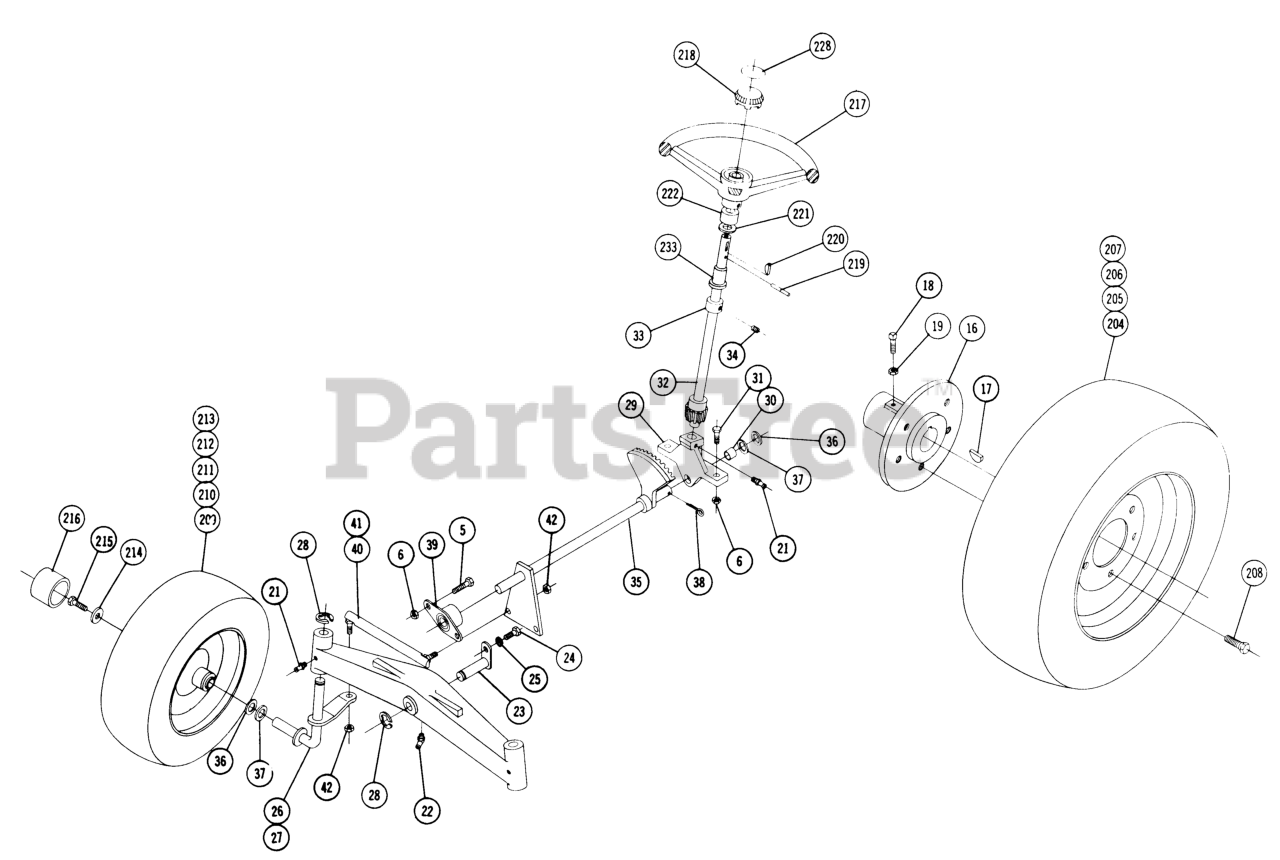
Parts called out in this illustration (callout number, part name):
1	Ass-y.Frame
2	Hoodstand
3	Nut, 1/4-20
4	Cover-Dust
5	Bolt 3/8-16 x 1
6	3/8-16 E.S.
7	Bolt 5/16-18 x
8	Nut-Nylok
9	Pulley
10	Set Screw
11	WOODRUFF KEY
12	Bolt 3/8-16 x 7/8
13	Lockwasher
14	Tool Box
15	Bolt 3/8-16 x 3/4
16	Hub Wheel
17	WOODRUFF KEY
18	Screw-Set
19	3/8-16 Jam Nut
20	AXLE-FRONT
21	Zerk
22	FITTING-GREASE
23	PIN AND PLATE ASM
24	Bolt Hex 5/16-18
25	Lockwasher
26	R.H. Spindle
27	L.H. Spindle
28	E-RING
29	Support
30	BEARING-BRONZE
31	Bolt 3/8-16 x 1
32	ASSY UPPER STEER R
33	Collar
34	Set Screw Nylok
35	Assy-Steering
36	WASHER-SHIM
37	WASHER
38	Cotter Pin
39	BEARING-FLANGED
40	Tie Rod-R.H.
41	Tie Rod-L.H.
42	Locknut 3/8-24
43	Pedal
44	BUSHING
45	Gasket
46	Hairpin
47	Hairpin
48	Roll Pin
49	Lift Lever
50	LOWER PLUNGER R
51	PLUNGER ROD
52	Roll Pin
53	SPRING-COMPRESSION
54	Guide-Rod
55	Cap
56	Grip
57	Hairpen
58	Quadrant
59	ROD-LIFT CONTROL
60	KNOB-LIFT CONTROL
61	Cap
62	Conduit
63	Hitch
64	Pin
65	RING-SNAP, EXTERNAL
66	SPACER
67	BATTERY BOX ASSY R (NS)
68	Nut-Nylok
69	LINK BATTERY CLAMP
70	Nut-Nylok
71	ever Brake
72	Washer
73	E Ring
74	Idler Arm
75	BUSHING-FLANGED
76	Bolt 1/4-20 X 3/4
77	Nut-Jam 1
78	Lockwasher
79	Handle-Brake
80	KNOB
81	Washer
82	SPRING-BRAKE
83	Idler Pulley
84	SPACER-BRAKE LINK
85	Bolt 3/8-16 x 1 5/8
86	Cam Control Arm
87	Indicator-Speed
88	Bolt, 1/4-x 1/2
89	Bearing
90	PIN
92	Cam Pivot Rod
93	FRICTION COLLAR
94	COLLAR BRKT PIVOT
95	FRICTION CONE
96	SPRING FRICTION
97	Collar Friction
98	Nut 3/1-10 Jam
99	WOODRUFF KEY
100	Cam Plate
101	Spacer
102	NYLINER BUSHING
103	SHIM-WASHER
104	Spring
105	Housing
106	Support-Fuel Tank
107	Bolt Hex 5/16-18
108	Bolt 1/4-20 x 5/8 Whizlock
109	Grommet
110	Panel
111	Plug Button
112	SPEED NUT
113	Screw-Self #10 10-16
114	Fuel Tank
115	Clamp-Tank
116	Cap
118	Nut Square
119	S/A FUEL VALVE
120	Hose
121	Clip
122	Fuel Hose
123	SPACER
124	CLAMP CORBIN 7/16
125	Nut 5/16-18
126	Ass-y Engine-Lauson
127	Bolt, 3/8-16 x 1/2
128	Base Engine
129	Nipple 3/8 x 5
130	ELBOW-STREET
131	Cap
132	MUFFLER
133	Nipple 1" Pipe x 2"
134	PULLEY
135	Key
136	Choke-Control
137	Control-Throttle
138	Lockwasher 9/16
139	RING NUT
140	SWITCH
141	Nut
142	Lockwasher 6/16
143	Insulator
144	Key-EL
145	Cigar Lighter
146	Knob & Plug
147	SHELL CLAMP
148	Socket
149	Nut #8-32
150	LOCKWASHER
151	Wire
152	Battery
153	Wiring Harness
154	Ground Wire
155	ASSY REFLECTOR HOUSI
156	WIRE ASSY
157	SPRING
158	BULB
159	Lens
160	Pan HD Swage
161	Switch
162	Harness
163	SPEED CLIP
164	CONNECTOR 3 WIRE
165	CLIP-WIRE
166	Base
167	Lens
168	Bulb
169	CONNECTOR 2 WIRE
170	Lockwasher 3/8
171	Bracket
172	Bolt, 5/16-18 x 1/2
173	Footrest R.H.
174	Footrest L.H.
175	BRACKET
176	Bolt-Carriage 5/16-18
177	Latch Fender
178	Spring
179	NYLINER BUSHING
180	Pin
181	BRACKET FENDER LATCH
182	Nut, 1/4-20
183	Cover Plate
184	Bolt, 1/4-20 Whizlock
185	Fender
186	SPACER
187	GROMMET
188	Seat
189	Washer
190	Ass-y Hood
191	Hood-Hinge
192	NYLINER BUSHING
193	Rod Pivot
194	LEVER HOOD LATCH
195	KNOB
196	SPIROL PIN
197	Roller Rubber
198	Roller
199	Nut-Hi Crown
200	SPEED NUT
201	Rod Latch
202	Hood Ornament
203	SPEED NUT
204	Wheel and Tire
205	Wheel
206	Tire
207	VALVE TUBELESS
208	Lug Nut
209	Wheel, Tire & Tube
210	WHEEL RIM
211	Bearing
212	Tire
213	Tube
214	WASHER
215	Bolt 3/8-16 x 7/8
216	Hub Cap
217	Steering
218	CAP INSERT
219	ROLL PIN 1/4 X 1-1/4
220	Key
221	WASHER-BOWED
222	COLLAR
223	Decal-"6"
224	Decal "10"
225	Decal Hood Trim R.H.
226	Decal Hood Trim L.H.
227	Decal
228	Decal
229	Decal Free Wheeling
230	Decal
231	Tool Pin
232	V BELT
233	Bushing
234	Bolt #10-32
235	Nut #10-32
236	Lockwasher #10
237	Mounting Pad
238	Belt Guard
239	Bolt Hex 7/16-4 x 3/4
